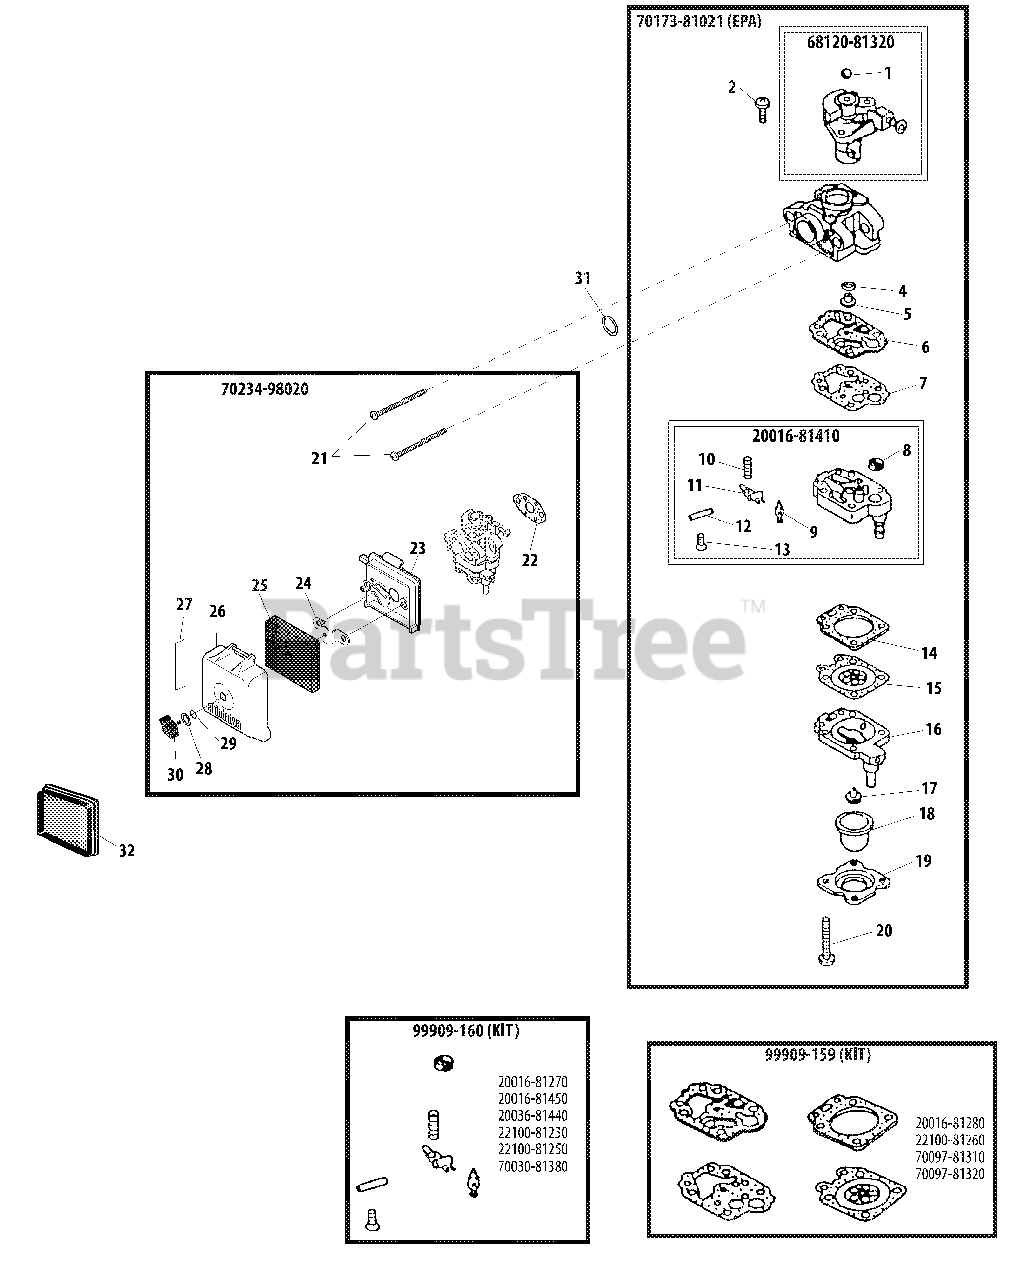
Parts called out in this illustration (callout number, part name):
1	BALL
2	SCREW
4	O-RING
5	JET, MAIN - 1000M #40
6	GASKET, PUMP
7	DIAPHRAGM, PUMP
8	STRAINER
9	VALVE, INLET NEEDLE
10	SPRING, METERING LEVER
11	LEVER, METERING
12	PIN, METERING LEVER
13	SCREW, METERING LEVER PIN
14	GASKET, METERING
15	DIAPHRAGM, METERING
16	BASE, PURGE
17	VALVE, CHECK
18	BULB, PURGE
19	RETAINER, PURGE BULB
20	SCREW, PUMP COVER
21	SCREW - 5X67
22	GASKET
23	CASE, AIR FILTER
24	PLATE, PREVENT
25	FILTER, AIR - FOAM
26	COVER, AIR FILTER
27	LABEL - CHOKE
28	WASHER - CONICAL
29	O-RING
30	THUMBSCREW
31	O-RING - 15
32	FILTER, AIR - HEAVY DUTY
20016-81410	PUMP BODY ASSY
68120-81320	VALVE, THROTTLE
70173-81021	CARBURETOR
70234-98020	AIR FILTER ASSY
99909-159	DIAPHRAGM/GASKET KIT
99909-160	REPAIR KIT
